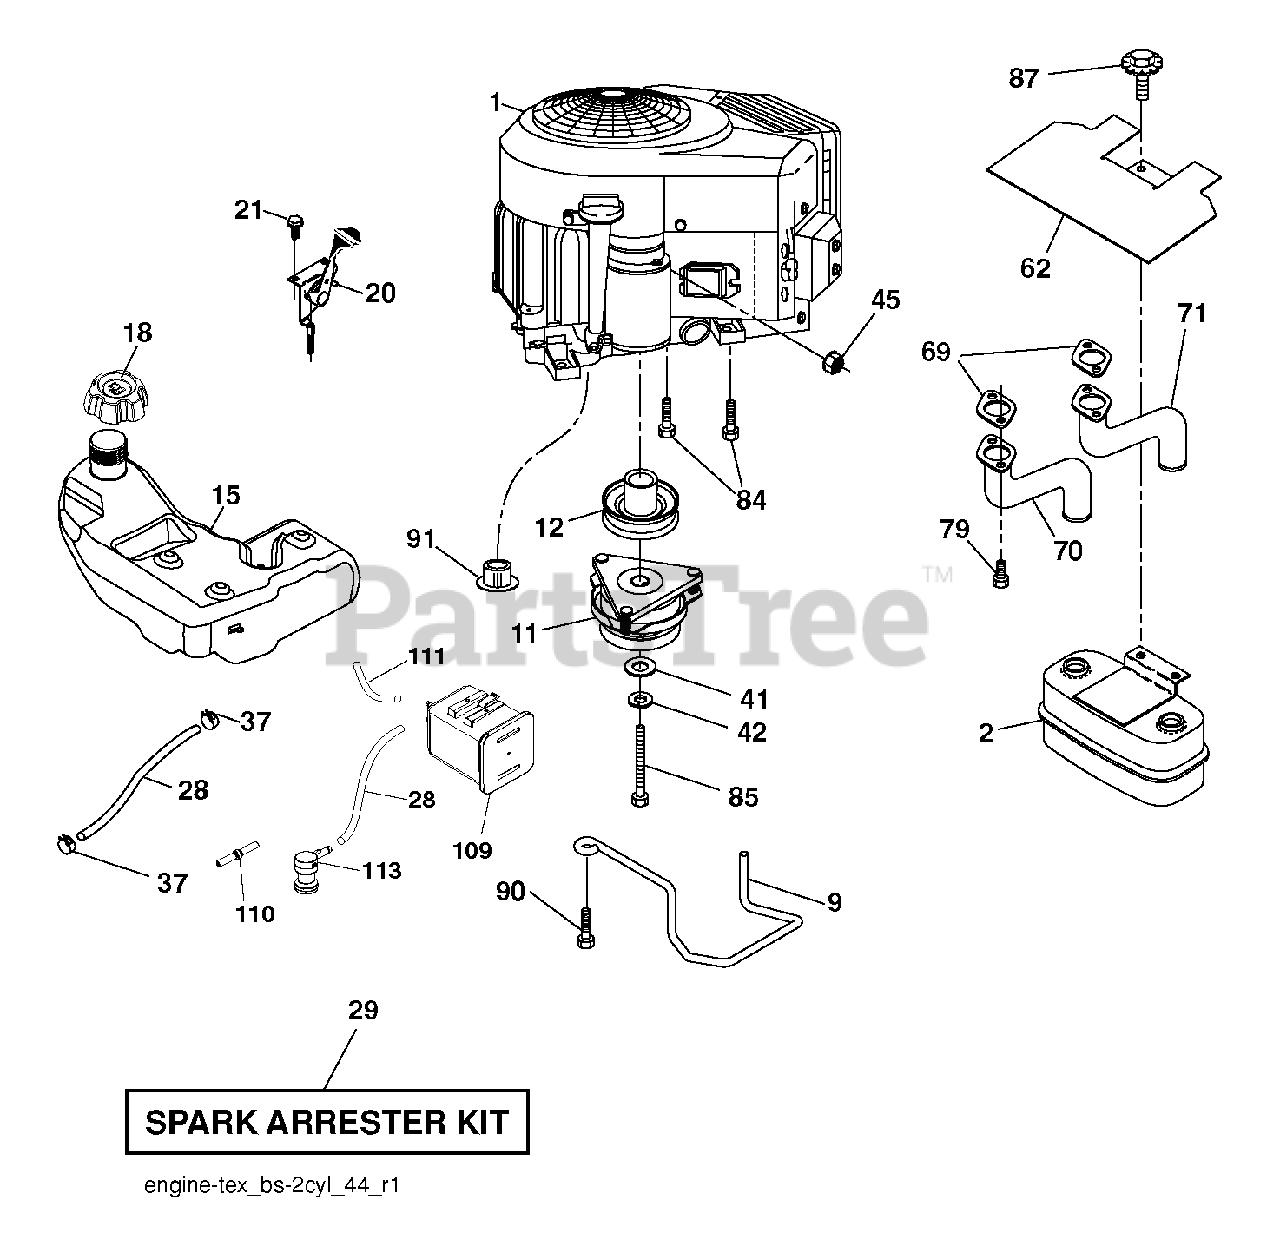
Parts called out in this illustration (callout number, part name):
2	MUFFLER.ASM.TWN.EXTNDED.DFLCTR
9	KEEPER.BELT.ENGINE.4.2
11	CLUTCH.ELECTRIC.LT.48"*
12	PULLEY.ENGINE.TUFFTORQ
15	TANK.ASM.FUEL.3GA.CARB
18	CAP.ASM.FL.RITCH.3"E10.SYM.498
20	CONTROL.TH/CK.COBRA.B&S.TWN.
21	SCREW.#10 X 0.750.BOS
28	LINE.FUEL.64"REAR.EMIS
29	KIT.SPARK ARRESTOR 794945 B&S
37	HOSE CLAMP
42	LOCKWASHER
45	NUT
62	SHIELD.HEAT.MUFFLER
69	GASKET.MUFFLER
70	RP.EXHAUST.TUBE.LH.BS/TWIN
71	EXHAUST.TUBE.RH.BS/TWIN
79	SCREW.SOCKET.HEAD.5/16-18
84	SCREW.3/8-16
85	BOLT HEX 7/16-20X4-1/4"
87	Bolt, 5/16-18 X 1-3/4
90	SCREW 3/8-16X1
91	BUSHING.1.375OD
109	CANNISTER, CARBON
110	VALVE.ASM.ANTI-SLOSH
111	RP PURGE LINE
113	VALVE.SLANT.CARTRDG.90 DEG.TEX
